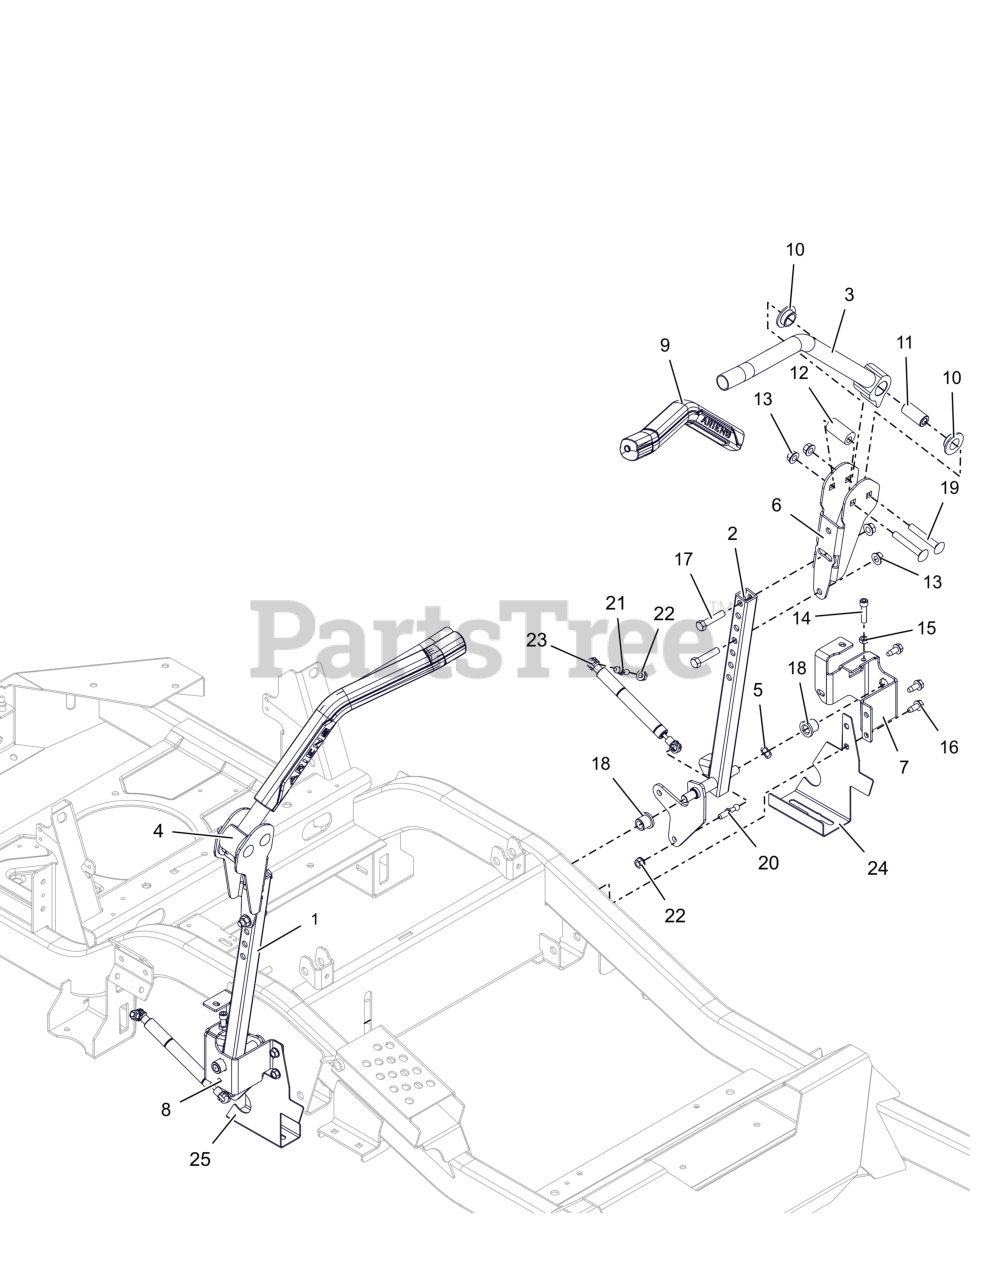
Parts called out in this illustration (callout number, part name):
1	WLDMT, STEERING RH
2	WLDMT, STEERING LH
3	WLDMT, CONTROL HANDLE-LH (BLACK)
4	WLDMT, CONTROL HANDLE-RH (BLACK)
5	WAVE WASHER .531X.781X.125FH
6	ADJ UPPER CONTROL ARM BRKT-BLK
7	BRKT, STEERING ARM MOUNT -LH
8	BRKT, STEERING ARM MOUNT -RH
9	GRIP- HANDLEBAR ARIENS
10	BSHG-FLG .762X1.48X.44 IGLIDER
11	SPACER, STEERING ARM
12	BSHG, ECCENTRIC.406X.875X1.625
13	NUT-LK-TOP-FLG .38-16 ZC120
14	BLT, SHCS .312-18X1.25 G8 SS
15	NUT-JAM .312-18 G2 ZCC
16	SCR,TAP .312-18X.75 HWH TR ZCC
17	BLT, HEX .38-16X1.75 G5 ZCC
18	BHSG-FLG .500X.750X.750X.125
19	BLT, RHSSN.38-16X2.50 G5 ZCC
20	STUD-BALL-THREADED
21	STUD- BALL
22	NUT,LK-CTR-FLG .31-18 GF ZCC
24	GUARD, FRAME RAIL BELT LH
25	GUARD, FRAME RAIL BELT RH
